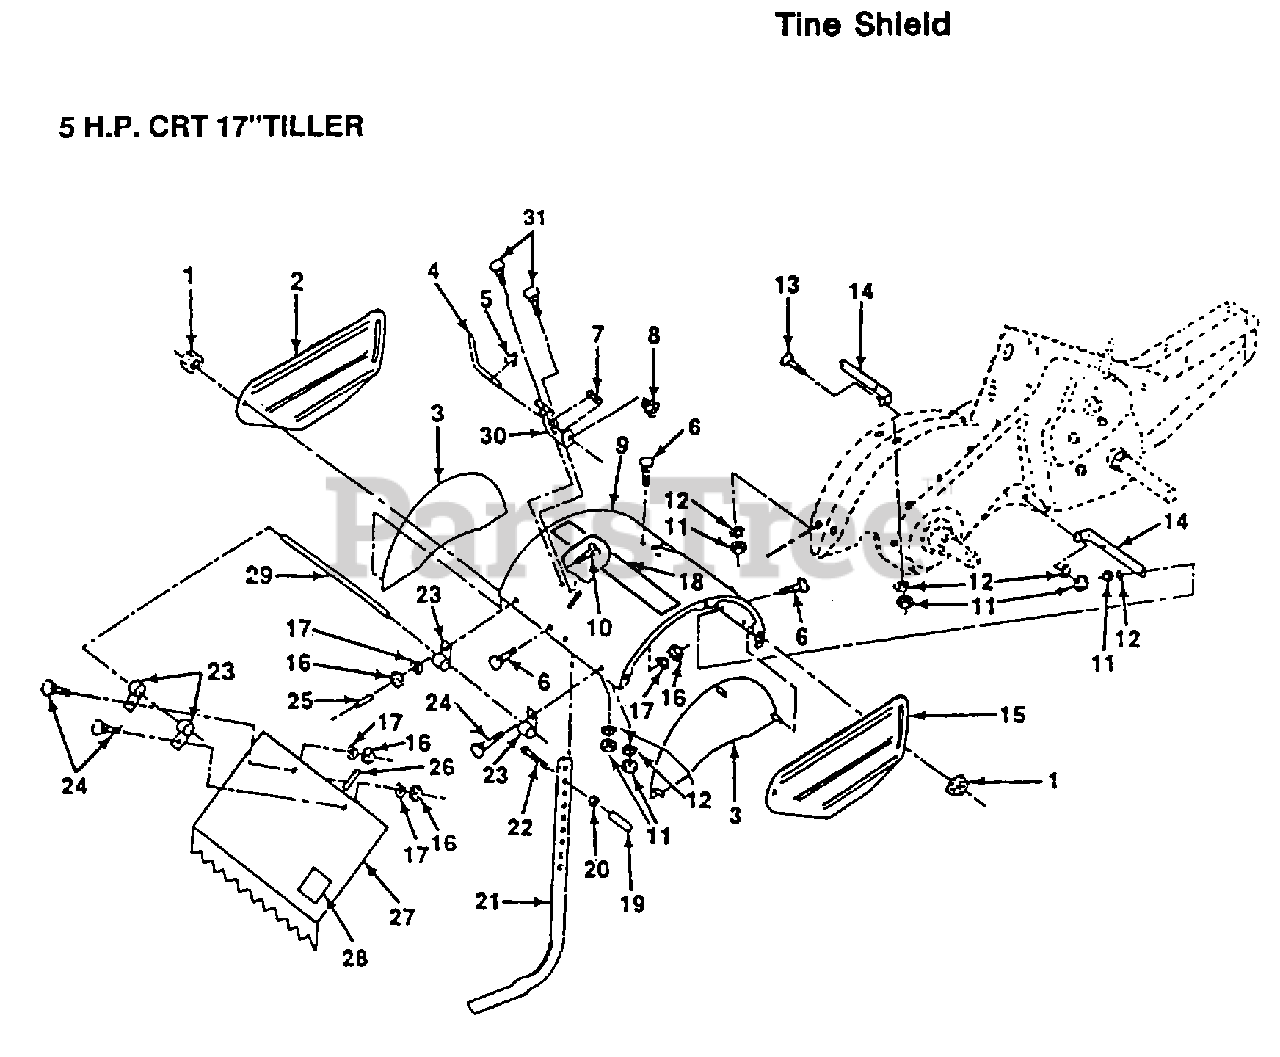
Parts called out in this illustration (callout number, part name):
1	NUT
4	STAKE PIN TI
5	KLIP RING TI
6	BOLT
7	SPRING TI
8	SPRING CRT
10	BOLT
11	LOCKWASHER
12	NUT.HEX.5/16-18
13	BOLT
14	BRKT SHIELD TINE
17	LOCKWASHER
19	GRIP CRT
20	NUT.HEX.3/8-16UNC
22	BOLT
23	HINGE CRT
24	BOLT
25	VINYL CAP TI
26	PAD IDLER TI
29	PIN HINGE
30	LATCH BRACKET TI
31	BOLT CRT
